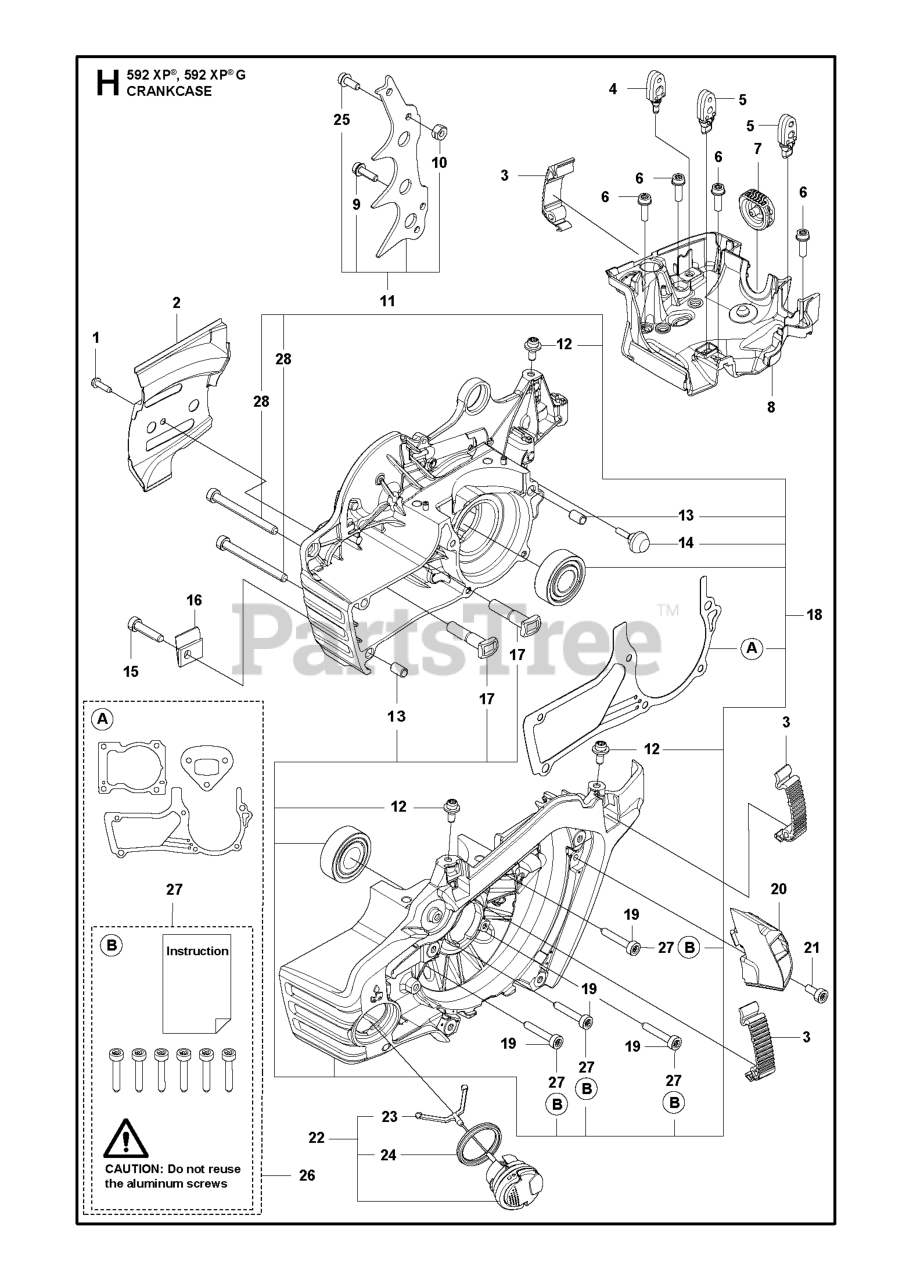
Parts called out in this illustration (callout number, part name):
2	CHAIN GUIDE PLATE BAR MOUNT
3	SNAP LOCKING GREY. ONLY USE F
5	DAMPER INLET SYSTEM
7	GROMMET THROTTLE WIRE
8	CARBURETTOR AREA BASE ASSY
9	SCREW
11	SPIKE KIT INNER NON - WRAP H58
12	SCREW ITXSCM WASHER M5X12 T27
13	GUIDE BUSHING
16	CHAIN CATCHER
18	CRANKCASE KIT 90CC SPARE PARTS
19	SCREW
20	AIR NOZZLE
21	SCREW ITXSCM
22	TANK CAP ASSY
26	GASKET KIT SPARE PART H592
27	SCREW KIT ALUMINUM 6 PCS
